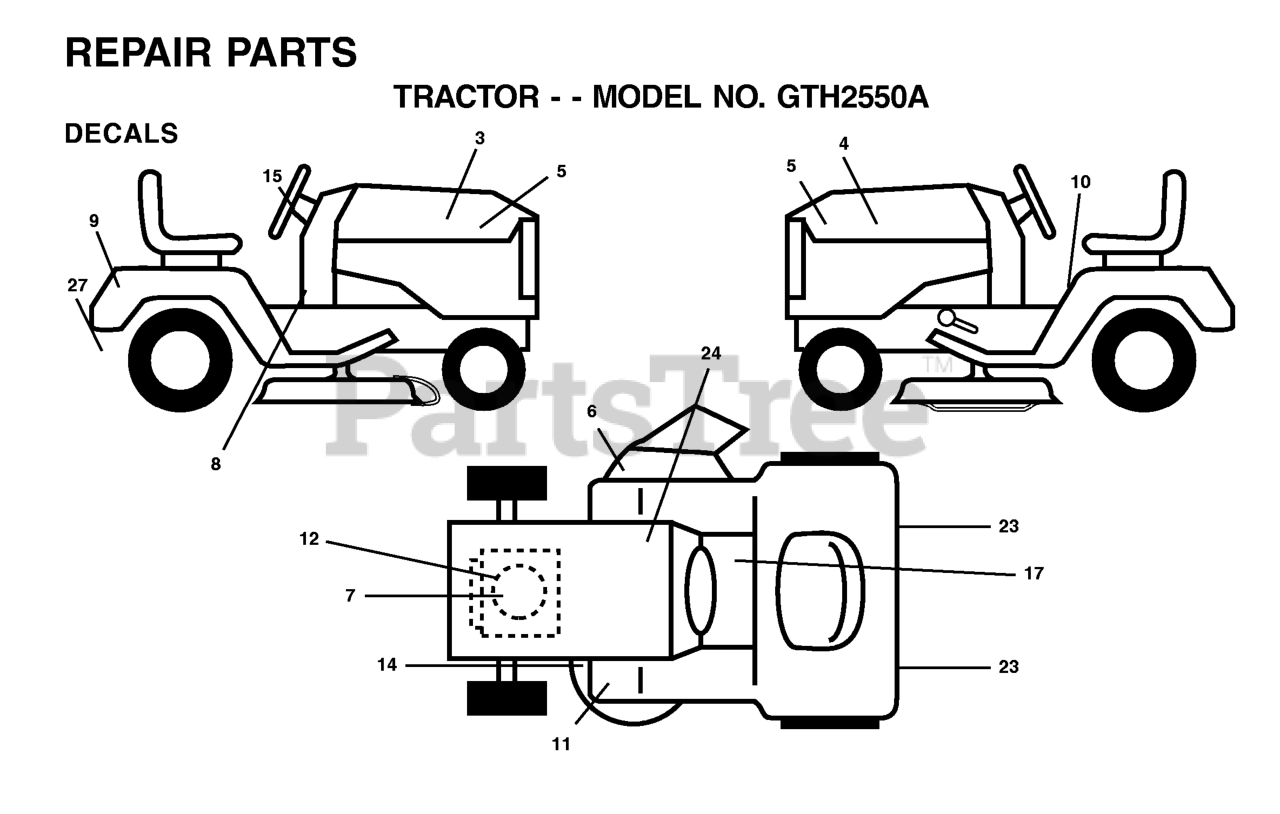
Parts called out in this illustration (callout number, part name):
6	DECAL.WARN.KEEP.HAND.AWAY
8	DECAL, DASH
9	DECAL, FENDER
10	DECAL FENDER DANGER
14	DECAL V-BELT SCHEMATIC
15	DECAL.WHEEL.STEERING.HUSQ.PERM
17	DECAL PARK BRAKE
23	REFLECTOR-TAIL YT
24	DECAL BTRY SYMBOLS
